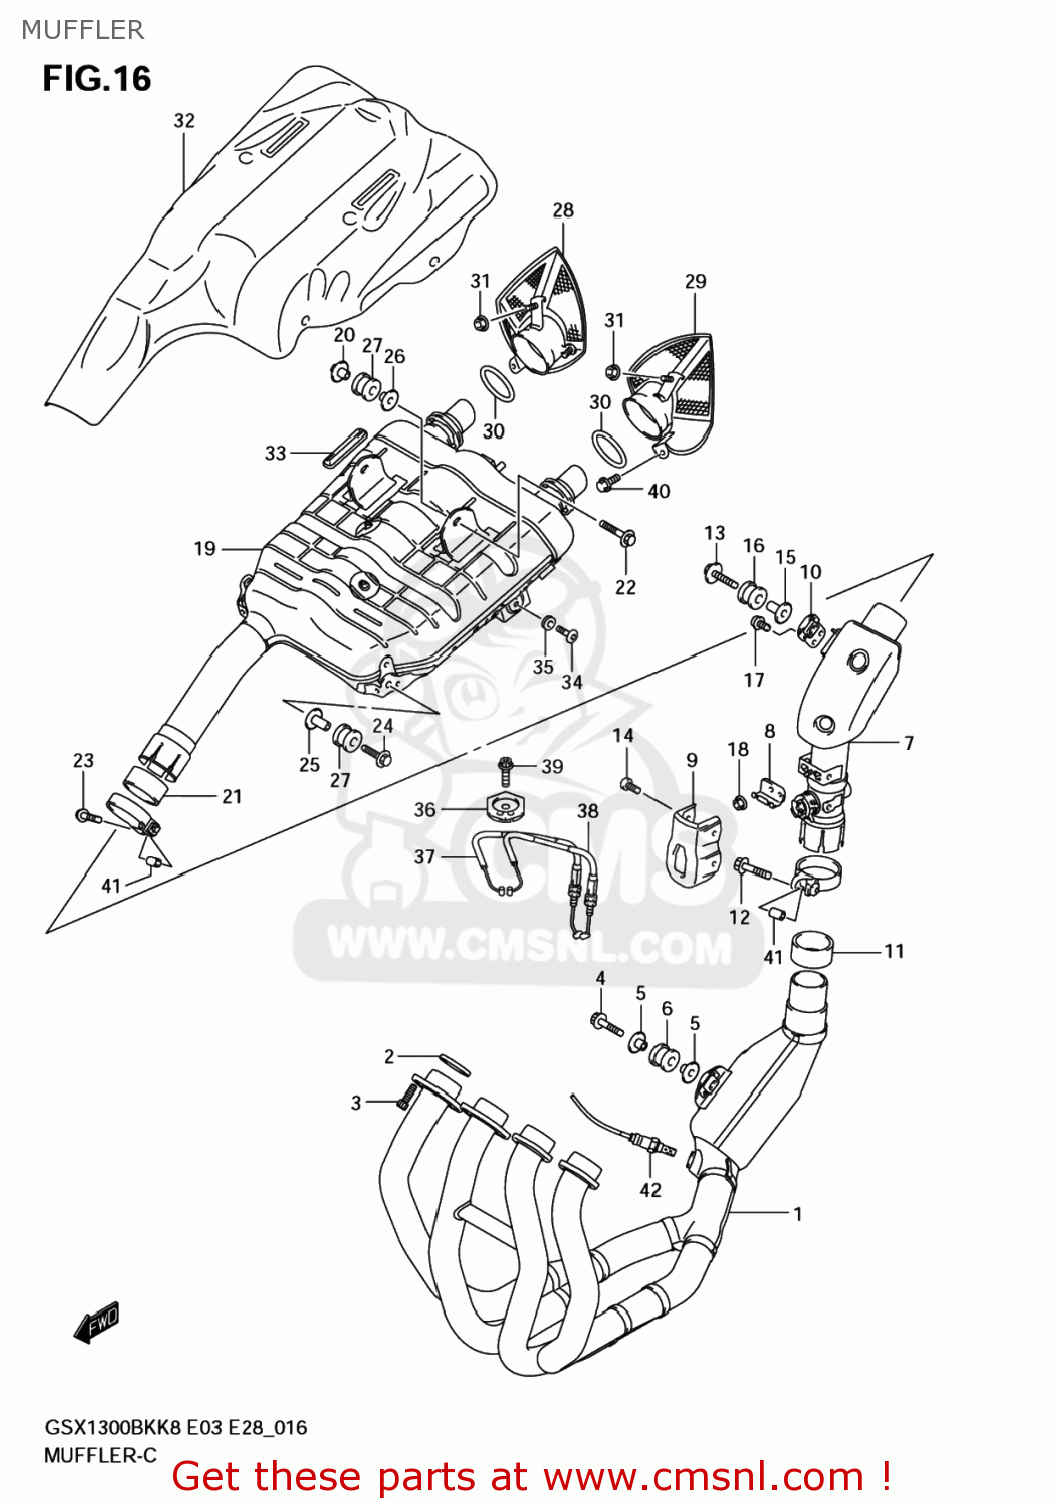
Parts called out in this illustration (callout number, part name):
1	PIPE,EXHAUST
2	GASKET,EXHAUST PIPE (NAS)
3	BOLT
4	BOLT(8X40)
5	SPACER(8.6X12X14.3)
6	CUSHION
7	JOINT
8	BRACKET,EXHAUST VALVE CABLE
9	COVER,EXHAUST VALVE
10	BRACKET,JT SPRT
11	CONNECTOR,MUFFLER
12	BOLT(8X40)
13	BOLT 8X45
14	SCREW(6X10)
15	SPACER(8.6X12X24.2)
16	CUSHION
17	BOLT
18	NUT
19	BODY,MUFFLER
20	NUT,MUFFLER SUPPORT
21	CONNECTOR,MUFFLER
22	BOLT(8X45)
23	BOLT(8X40)
24	BOLT 8X40
25	SPACER(8.6X12X24.2)
26	SPACER(8.6X12X14.3)
27	CUSHION
28	PLATE,MUFFLER RR,R
29	PLATE,MUFFLER RR,L
30	O RING(D:5.7,ID:47.6)
31	NUT
32	GUARD,MUF HEAT
33	CUSHION,HEAT GUARD
34	SCREW(6X12)
35	CUSHION
36	PULLEY CONTROL
37	CABLE,EXHAUST VALVE NO.1
38	CABLE,EXHAUST VALVE NO.2
39	BOLT
40	BOLT
41	SPACER,MUFFLER
42	SENSOR,OXYGEN
